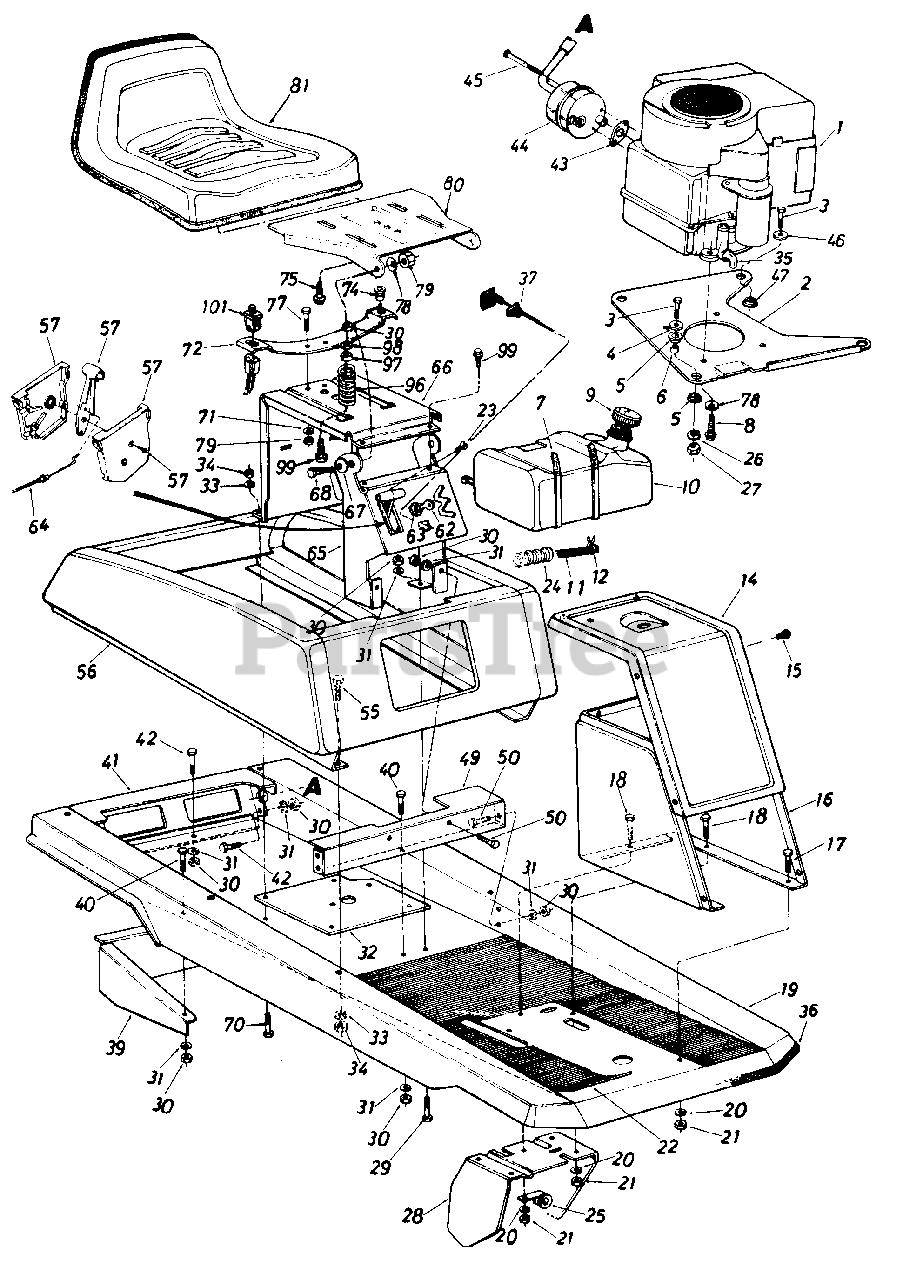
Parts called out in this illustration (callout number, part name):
1	Engine
4	Fl-Wash. .330" I.D. x 1.125" O.D.
5	Engine Mounting Grommet
6	Spacer .315" I.D. x .50" O.D. x.520" Lg.
7	Cable Tie 30.6 Lg.
8	Hex Wash. Hd. Self-Tap Scr. 3/8-16 x 1.25" Lg.
9	Gas Gauge
10	Fuel Tank
11	Fuel Line-26" Lg.
12	Hose Clamp-1/2" O.D. Tube
22	Floor Mat
23	Truss Mach. AB-Tap Scr. #10 x 50" Lg.
24	Convoluted Conduit
25	Clamp
26	L-Wash. 5/16" I.D.
27	Hex Nut 5/16-24 Thd.
28	Clutch-Brake Pedal Ass'y.
29	Hex Bolt 5/16-18 x 75" Lg
30	Hex Nut 5/16-18 Thd.
31	L-Wash. 5/16" I.D.
32	Mounting Brkt. Variable Speed Pulley
33	L-Wash. 1/4" I.D.
34	Hex Nut 1/4-20 Thd.
35	90ø Elbow Male To Female
36	Trim Strip 18" Lg.
37	Choke Control
43	Exhaust Gasket
44	Muffler Ass'y.
45	Shld. Bolt
46	Fl-Wash. .330" I.D. x 1.25" O.D.
47	Flange Wash. .320" I.D. x .750" O.D.
49	Seat Support & Frame Brkt.
50	Hex Bolt 5/16-18 x .75" Lg.
55	Hex Bolt 1/4-20 x .50" Lg.
57	Throttle Control Box Ass'y.
62	Ignition Key
63	Ignition Switch
64	Throttle Control Wire
68	Hex Bolt 5/16-18 x .75" Lg.
70	Hex Tap Scr. 1/4-20 x 1.0" Lg.
71	L-Wash. 5/16" I.D.
72	Seat Spring
74	Grommet
75	Hex Wash. Hd. Tap Scr. 3/8-16 x 3/4" Lg.
77	Hex Bolt 5/16-18 x .75" Lg.
78	Bell-Wash. .345" I.D. x .88" O.D.
79	Hex Cent. L-Nut 5/16-18 Thd.
80	Seat Pivot Bracket
81	Seat Ass'y. Comp.
96	Compression Spring 2.7" Lg.
97	Bushing
98	Fl-Wash. .344" I.D. x .875"
99	Hex Bolt 5/16-18 x 1" Lg. (Grade 5)
101	Seat Switch
